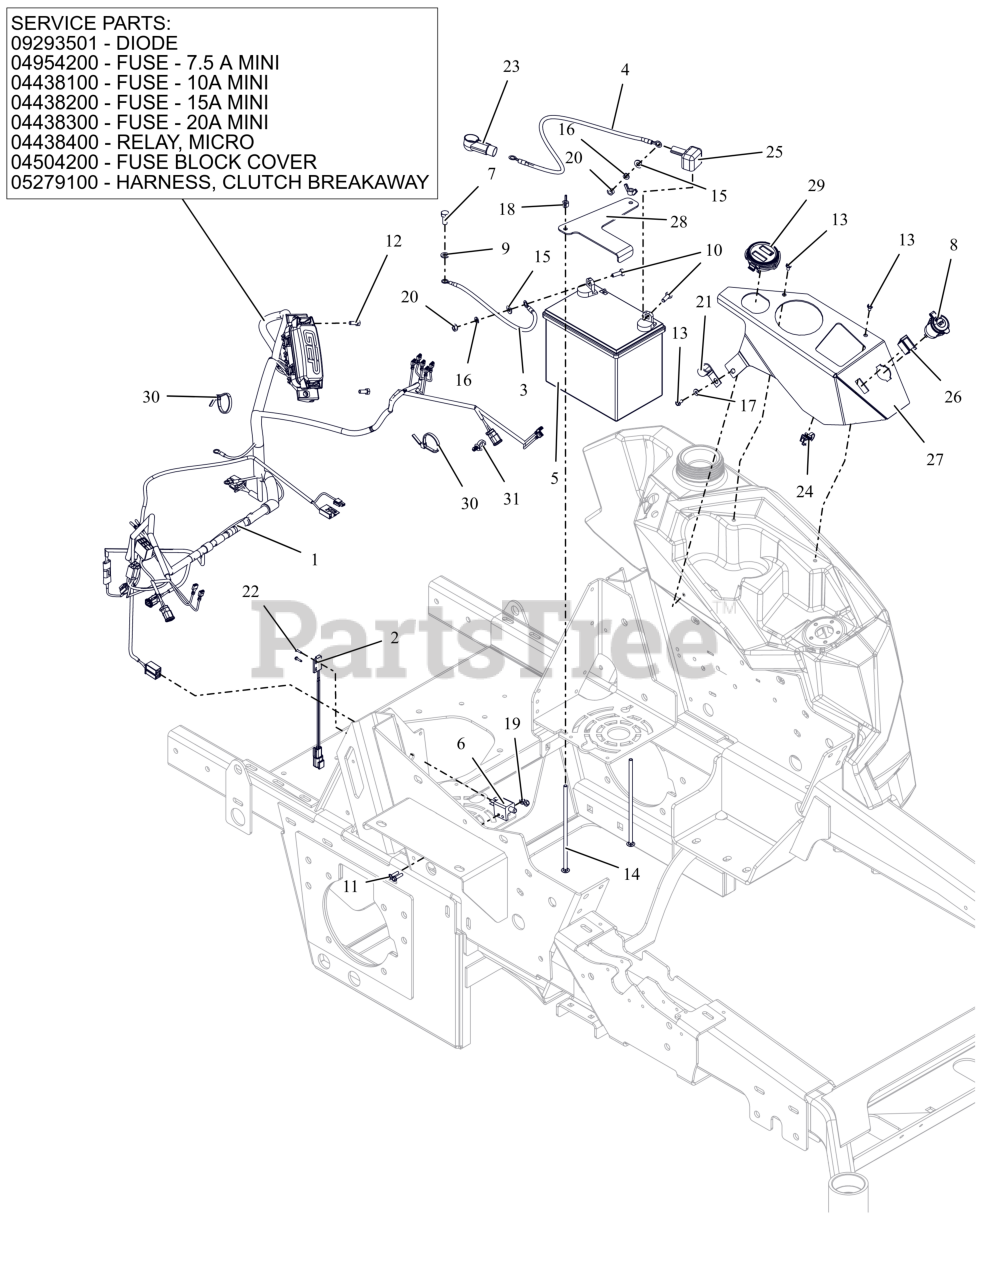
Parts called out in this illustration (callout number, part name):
1	KIT- PT600 HARNESS ROUTING
1	DIODE, CONNECTOR SHELL
1	FUSE, 7.5 AMP MINI-ATC
1	FUSE,10 AMP MINI-ATC
1	FUSE,15 AMP MINI-ATC
1	FUSE,20 AMP MINI ATC
1	RELAY,MICRO5 TERML W/RESISTOR
1	COVER, HARNESS FUSE/RELAY MOD
1	HARNESS, CLUTCH BREAKAWAY
2	SWITCH, MAGNETIC
3	CABLE, NEGATIVE BATTERY 11.5 LNG
4	CABLE, POS W/(2) .312 RING 16.0 LG
5	BATTERY, 300 CCA 10U1L
6	SWITCH- DOUBLE POLE N.O./N.O.
7	BLT, HEX M8-1.25X20 G8.8 ZCC
8	PORT, 12 VOLT POWER
9	WSHR,LK-REG .312X.078 ZCC
10	BLT, HEX .25-20X.75 G5 ZCC
11	BLT, HWH #10-24X.75 ZCC
12	BLT, HEX M6-1X16 G8.8 ZCC
13	SCR-MCH 10-24X.38 HWHSTAINLESS
14	BTL,RHSN .250-20 X 7.5 G5 ZCC
15	WSHR,FLT .281X.625X.065 ZCC
16	WSHR,LK-REG .250X.062 ZCC
17	WSHR-FL-STL .196X.50X.06 ZC120
18	NUT, LK-WING .25-20 ZCC
19	NUT-LK-NYL #10-24 G2 ZCC
20	NUT-STD .250-20 G2 ZCC
22	SCR-TAP #4-40X.50 HWH ZCC
23	BOOT, .65ID POS
24	TIE, EC23 MOUNT W CABLE
25	INSULATOR
26	SWITCH,BLANK
27	PANEL, LH CONTROL (RED)
28	HOLDDOWN, BATTERY (BLACK)
29	DUAL METER
30	CABLE TIE LG 5-1/2
31	CLIP- PUSH-IN X-MAS TREE CABLE
